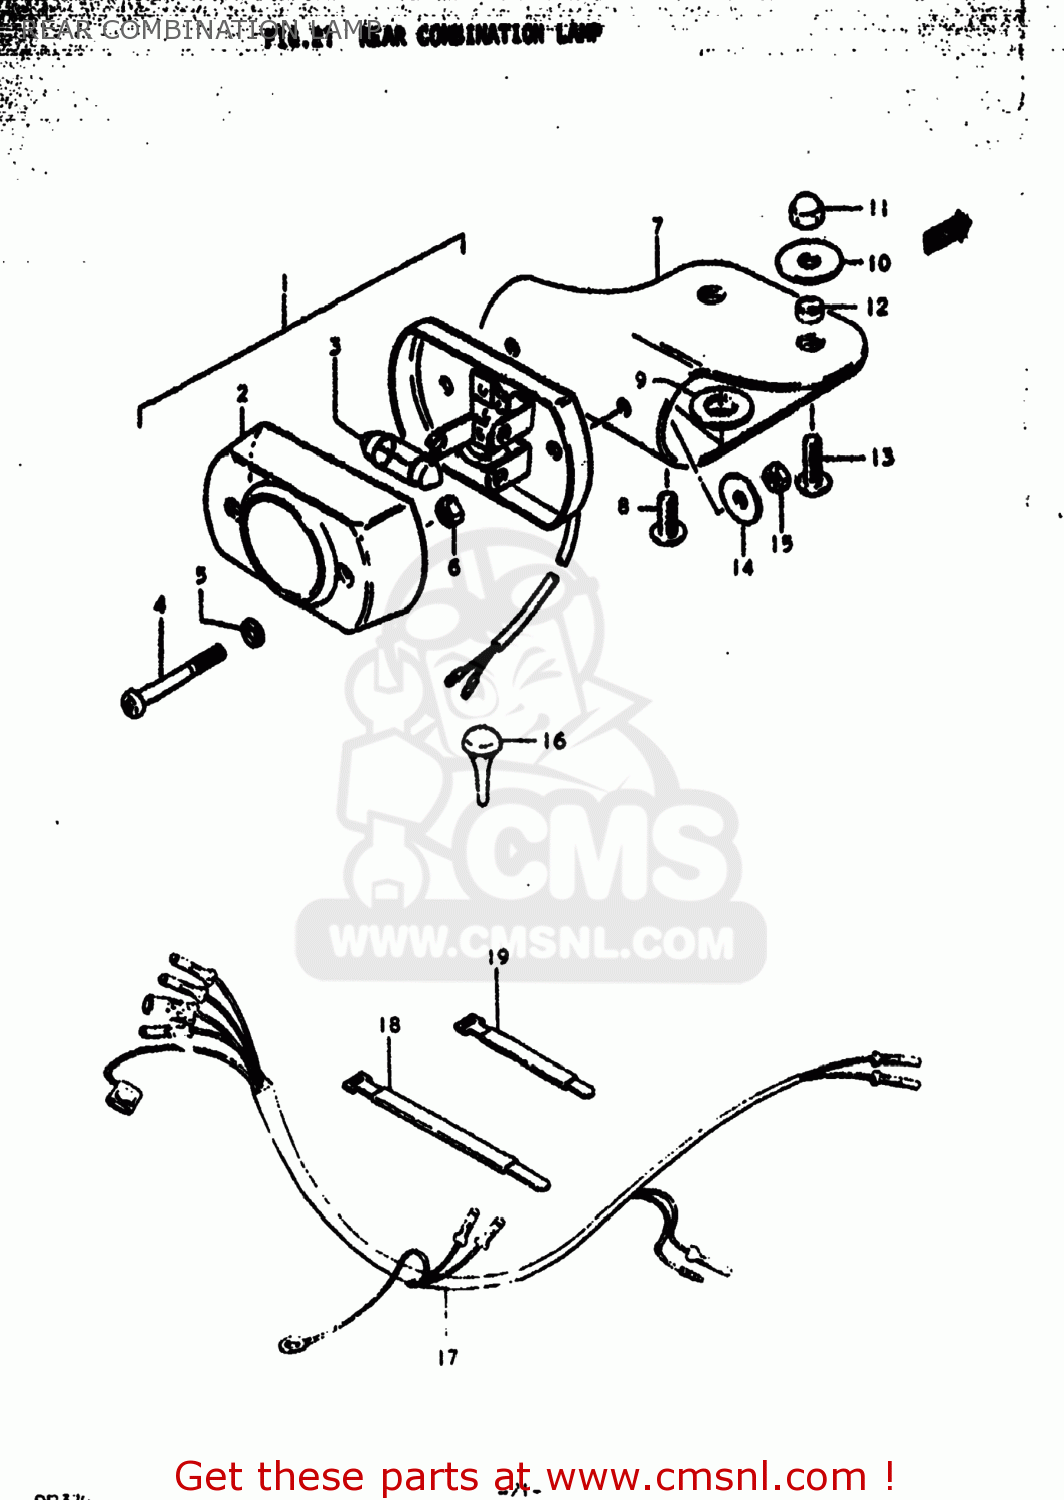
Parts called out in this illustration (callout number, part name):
1	LAMP ASSEMBLY,REAR COMBINATION
2	LENS,REAR COMBINATION LAMP
3	BULB
4	SCREW,REAR COMBINATION LAMP LENS
5	WASHER,REAR COMBINATION LAMP
6	NUT 4MM
7	CUSHION,REAR COMBINATION LAMP
8	SCREW 6X12
9	WASHER
10	WASHER (6.5X20X1.2)
11	NUT
12	SPACER(6.2X8.3X5.7)
13	SCREW 6X12
14	WASHER(5.2X16X1)
15	NUT
16	CUSHION
17	HARNESS,WIRING
18	CLAMP
19	CLAMP
